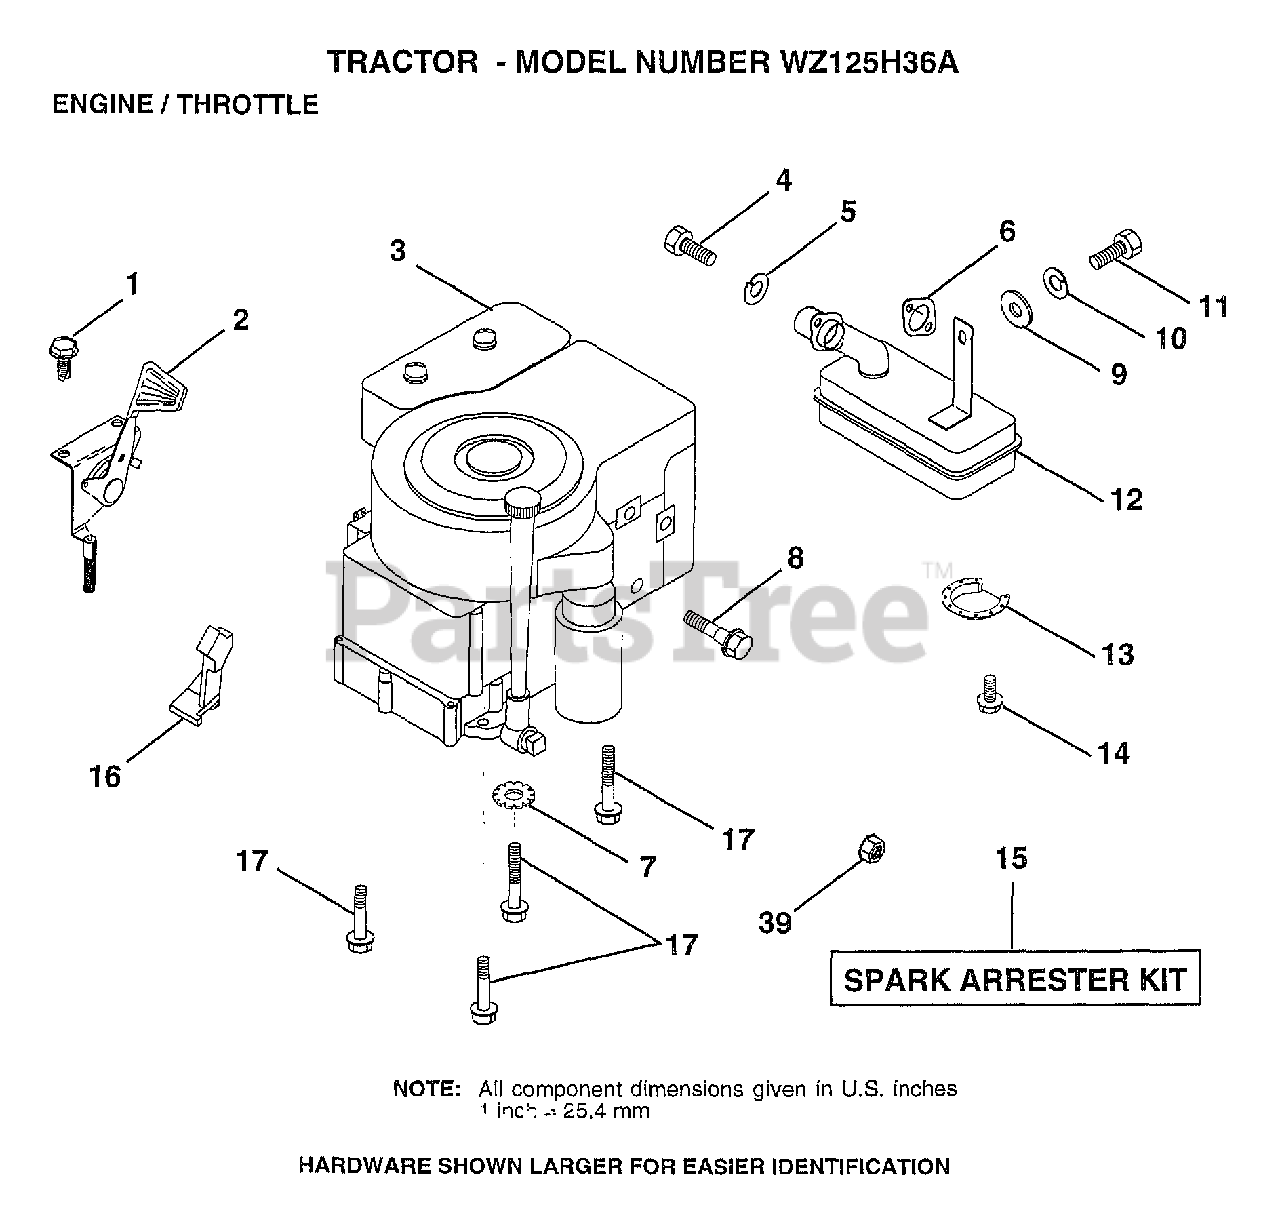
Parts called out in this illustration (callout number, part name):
1	SCREW.1/4-20X1/2
4	SCREW
5	LOCKWASHER
6	GASKET ENG 1 313 LD TIN PLATED
7	LOCKWASHER
8	BOLT T
10	LOCKWASHER
12	MUFFLER
13	DEFLECTOR.222573
16	"STOP,DASH THROTT"
17	SCREW LT
39	NUT
